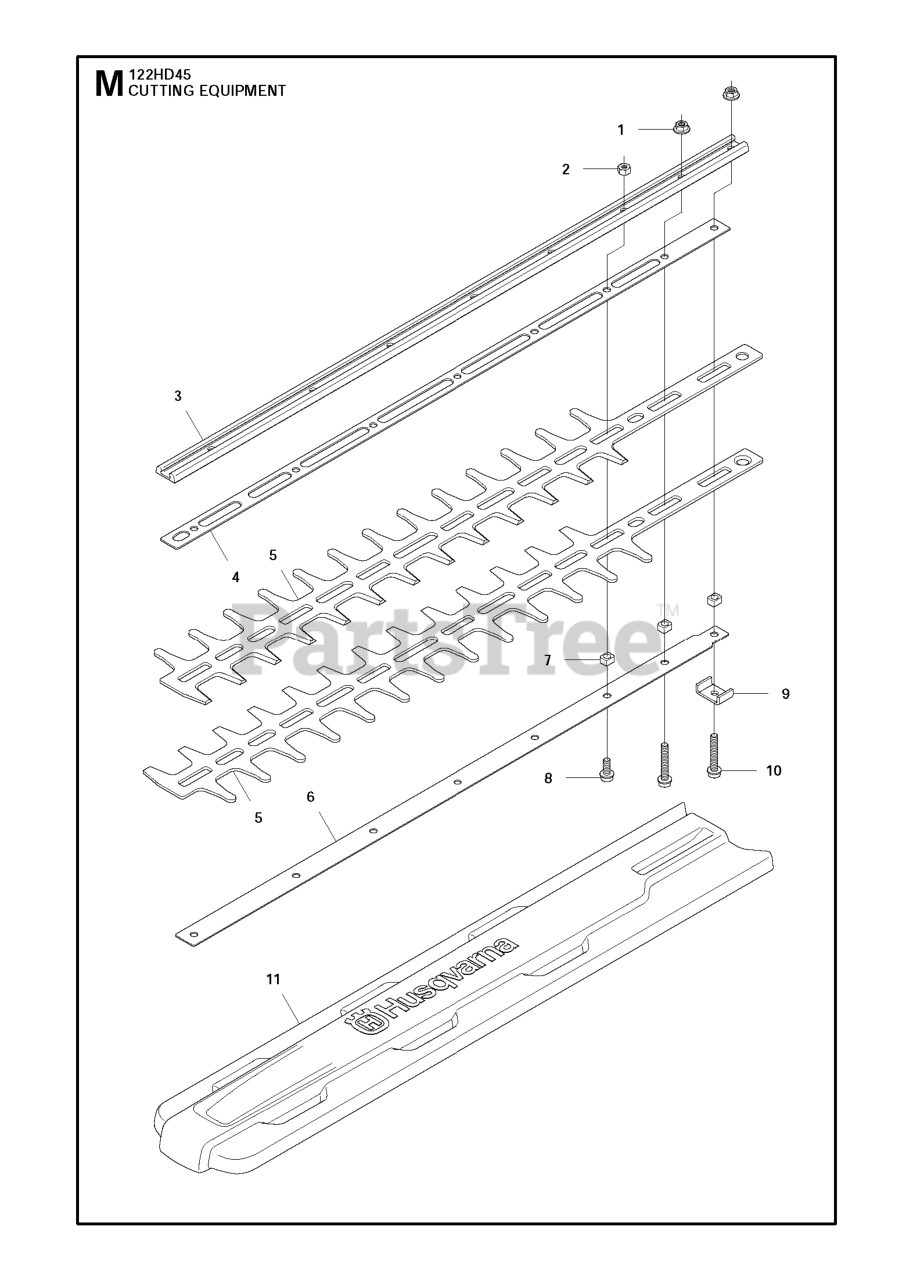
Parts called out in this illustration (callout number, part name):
4	WEAR PLATE
5	BLADE HEDGE TRIMMER
8	SCREW
11	TRANSPORT GUARD
